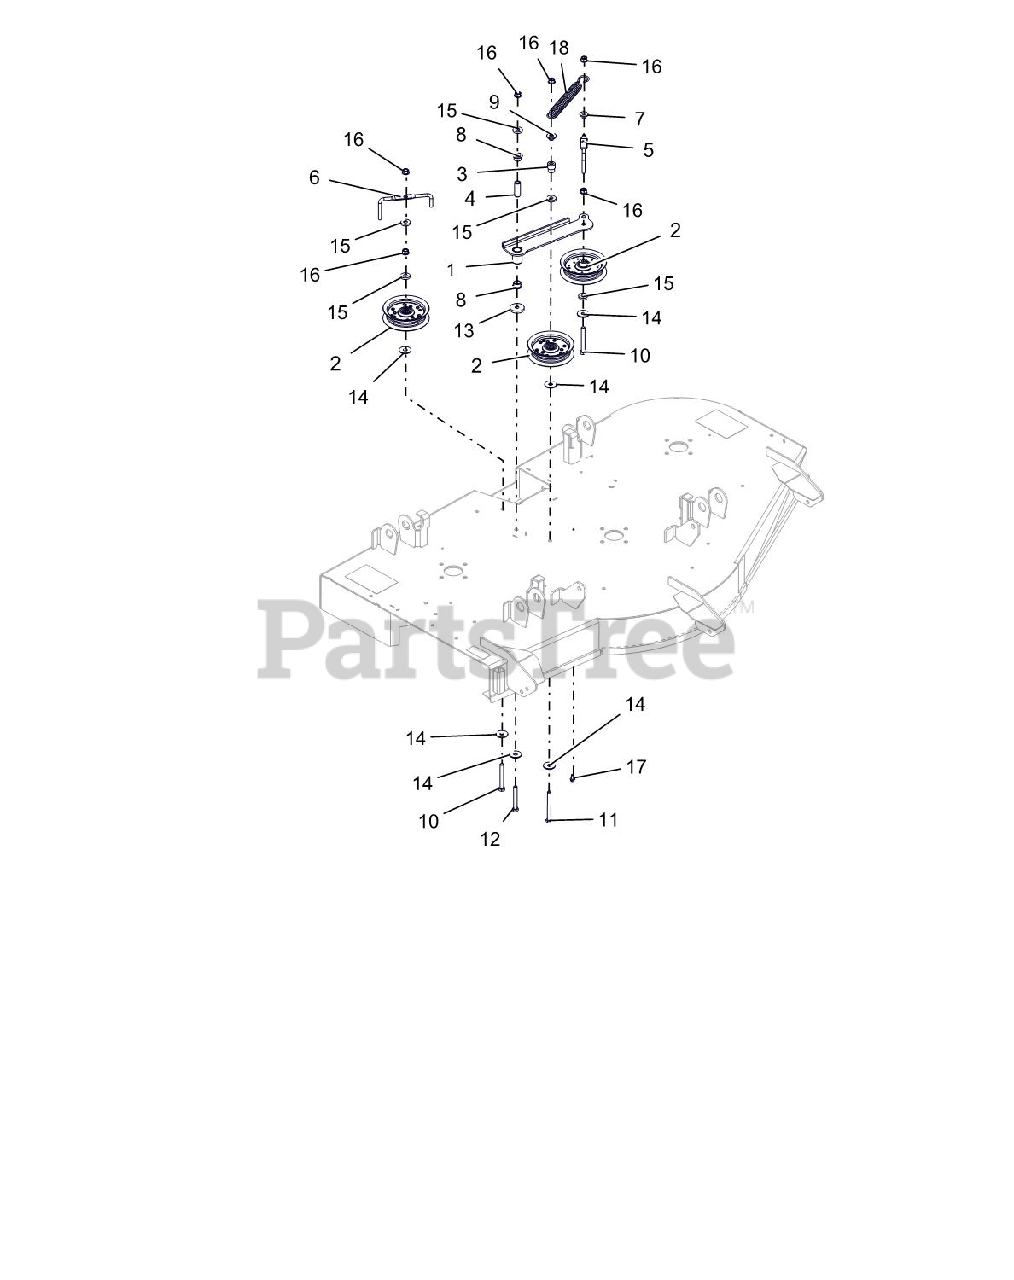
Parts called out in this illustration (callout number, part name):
1	WLDMT, IDLER ARM-52"
2	ASM, IDLER 4"
3	BUSHING, IDLER (P/M)
4	SPACER, .375IDX.625ODX1.66 PM
5	WIREFORM, BELT FINGER
6	WIREFORM, BELT FINGER
7	BSHG-FLG .385X.500X.875X.406
8	BSHG-FLG, .625X.750X.500X1.00
9	BSHG-FLG .385X.500X.875X.31
10	BLT-HEX .38-16X3.00 GR5 FTH YZ
11	@BLT-HEX .38-16X3.50 GR5 YWZC
12	@BLT-HEX .38-16X2.75 GR5 YWZC
13	WSHR,FLT STL.406X1.50X.245YWZC
14	WSHR-FL-STL .406X1.25X.10 ZC
15	WSHR-FL-STL .406X1.00X.188 YWZ
16	@NUT-LK-TOP-FLG .38-16 YWZC
17	SCR-TAP .25-20X.50 HWH TR YWZ
18	SG-TENS .135X.98X6.0 WLD 62
